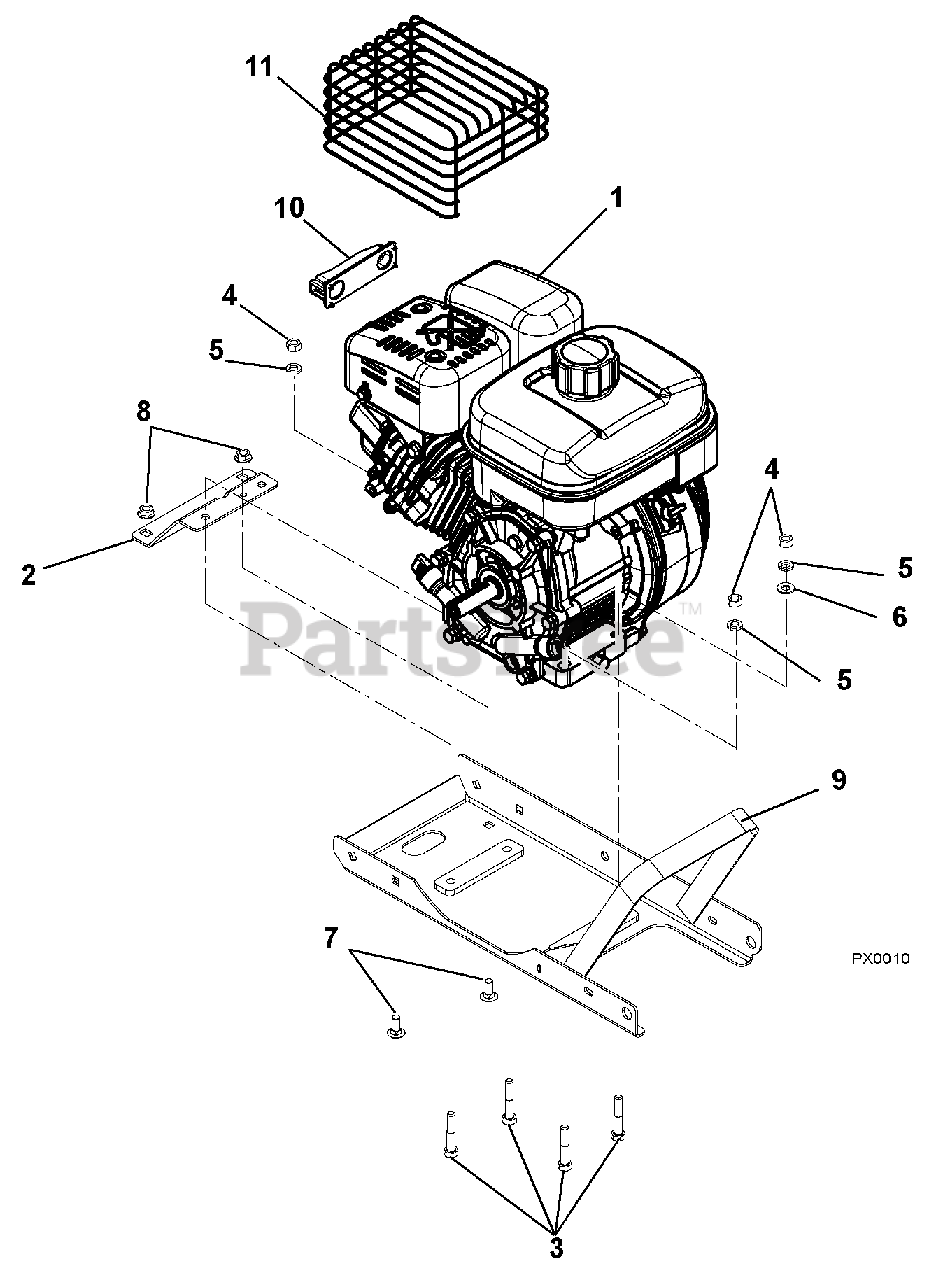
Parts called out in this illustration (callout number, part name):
1	Engine, Subaru SP170 (CARB) (986102)
2	Bracket, Reinforcement
3	Bolt, Hex .31-18 x 1.75 Grade 5
4	Nut, Hex .31-18
5	Washer, Locking .312 x .097
6	Washer-Flat-Steel .344 x .688 x .065
7	Bolt, Round Head Square Neck .31-18 x .75
8	Nut, Locking Top Flange .31-18
9	Frame, Edger
10	Kit, LCT Exhaust Deflector (986104)
11	Guard, Muffler Subaru (986501)
